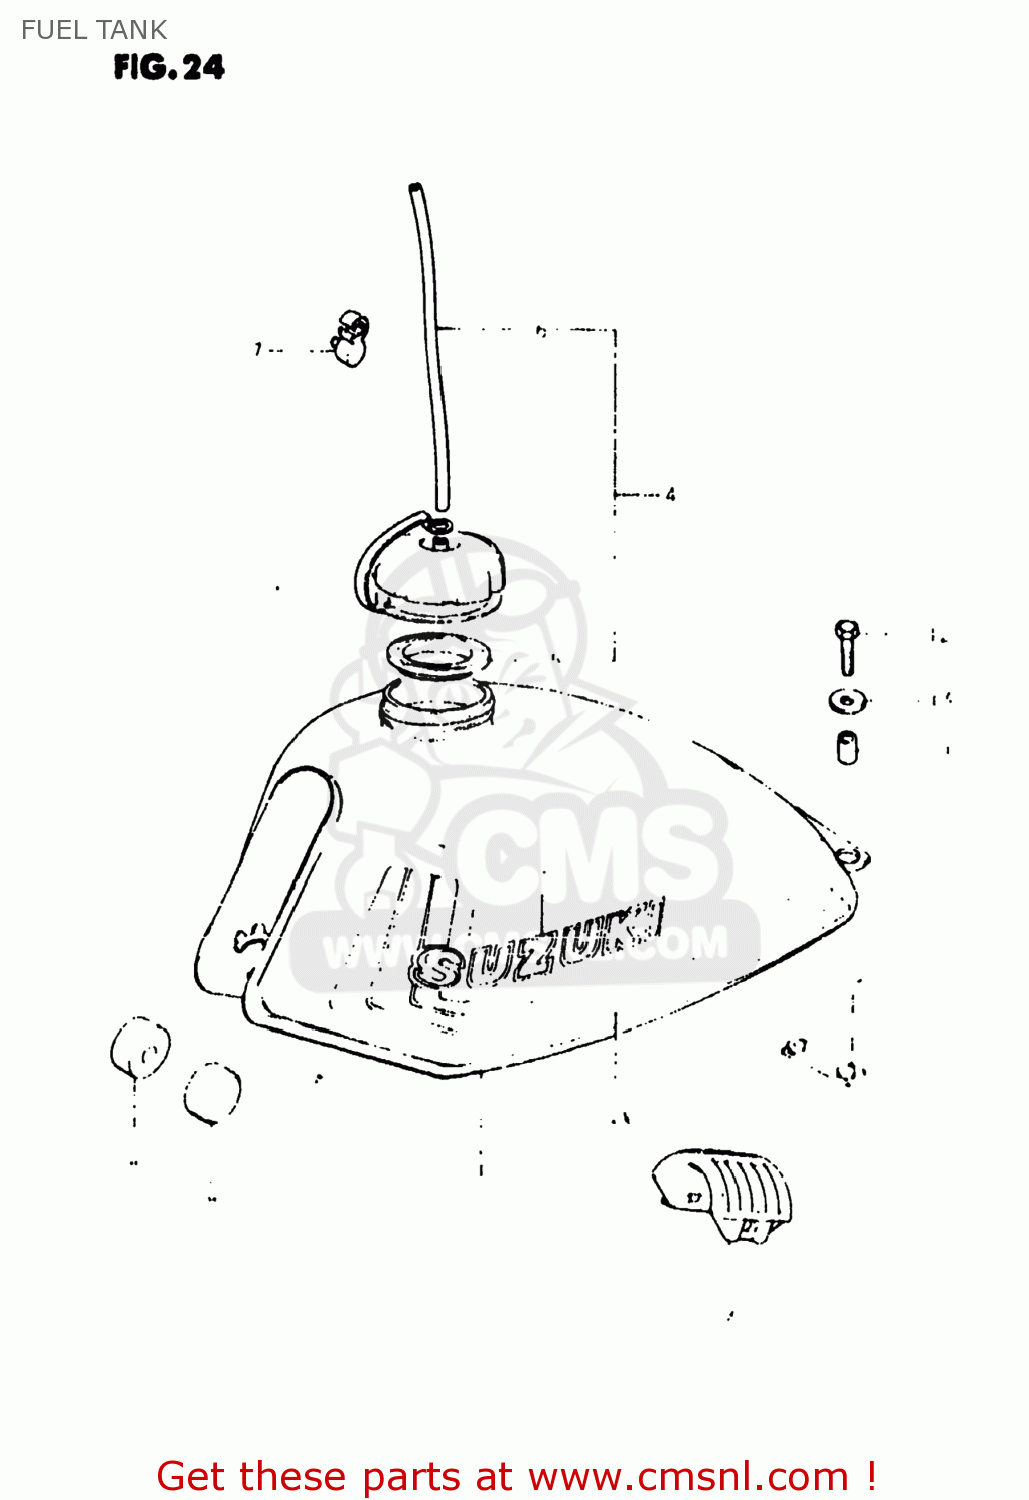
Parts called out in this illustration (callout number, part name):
1	TANK ASSEMBLY,FUEL
2	TAPE SET,FUEL TANK STRIPE
3	EMBLEM,FUEL TANK
4	CAP SET,FUEL TANK
5	GASKET,FUEL TANK CAP (NAS)
6	HOSE
7	CLAMP,FUEL TANK BREATHER HOSE
8	CUSHION
9	CUSHION,FUEL TANK
10	CUSHION,FUEL TANK,REAR
11	SPACER (6.1X8X12)
12	BOLT
13	WASHER (6.5X24X1.6)
